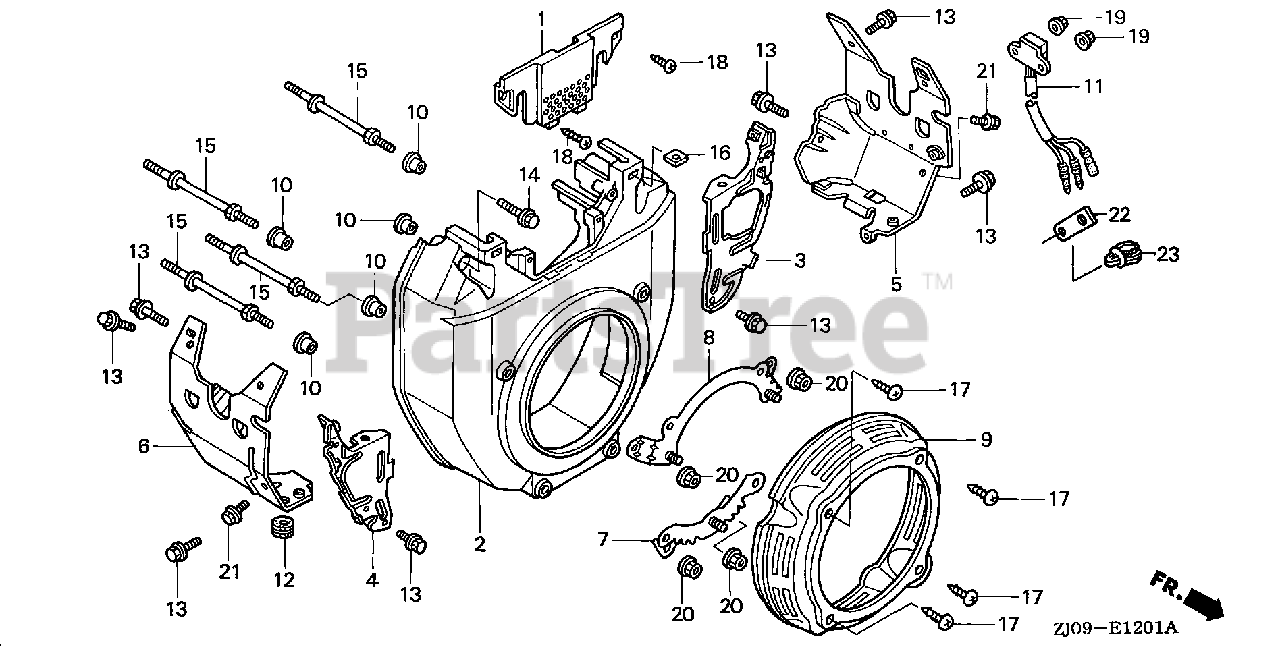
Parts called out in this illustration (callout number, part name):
1	COVER, FUEL PUMP (MANUAL CONTROL)
2	COVER, FAN *R8* (RECOIL STARTER) (BRIGHT RED)
3	PLATE, R. SIDE
4	PLATE, L. SIDE
5	SHROUD, R. (OIL ALERT)
6	SHROUD, L.
7	STAY A, RECOIL STARTER
8	STAY B, RECOIL STARTER
9	COVER, RECOIL STARTER STAY *R8* (BRIGHT RED)
10	COLLAR B, TAILLIGHT
11	ALERT UNIT ASSY., OIL
12	RUBBER, RR. FENDER CUSHION
13	BOLT, FLANGE (6X12) (CT200)
14	BOLT, FLANGE (6X23)
15	BOLT, STUD (6X71)
16	NUT, SQUARE (5MM)
17	SCREW, TAPPING (5X16)
18	SCREW, TAPPING (5X20)
19	NUT, FLANGE (5MM)
20	NUT, FLANGE (6MM)
21	BOLT, FLANGE (6X8)
